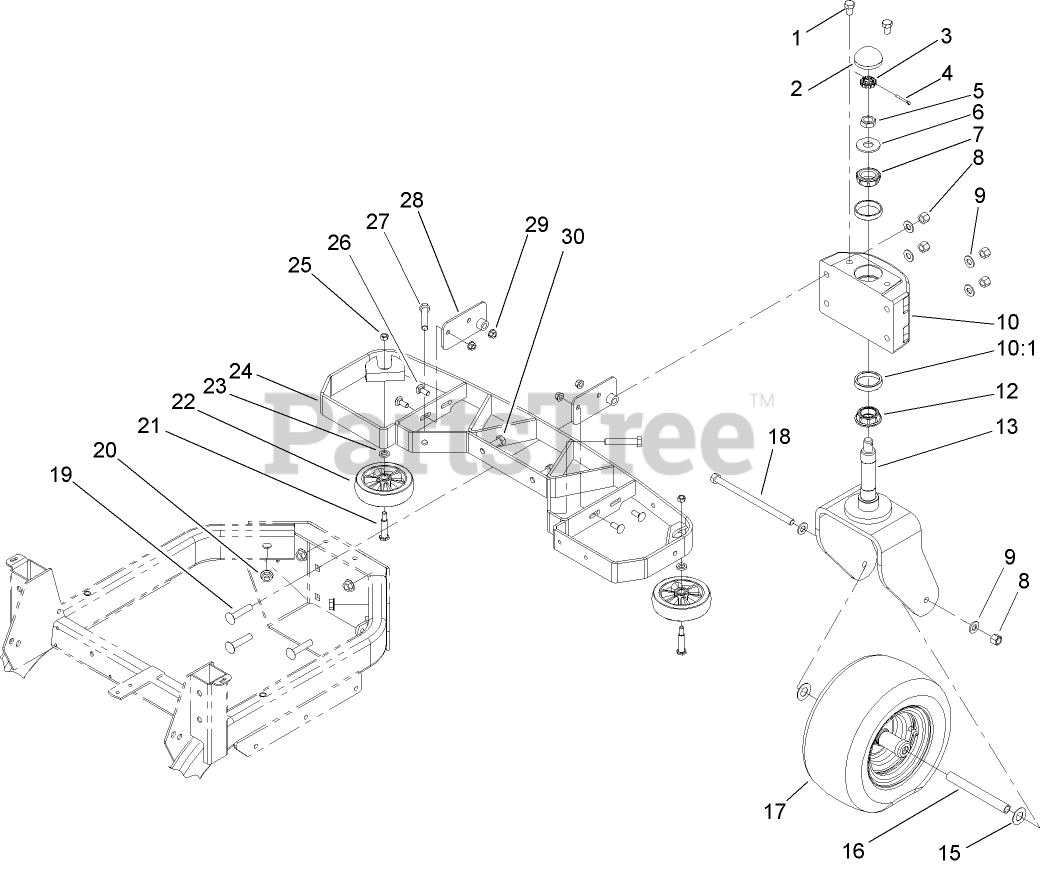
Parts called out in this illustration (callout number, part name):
1	SCREW-HH
2	DUSTCAP
3	NUT-LOCK, RETAINER
4	PIN-COTTER
5	NUT-JAM
6	WASHER-FLAT
7	BEARING-ROLLER, CONE
8	NUT-LOCK, NI
9	WASHER-FLAT
10	SPINDLE HOUSING ASM
10:1	CUP-BEARING, ROLLER
12	BEARING-CONE
13	CASTER FORK ASM
15	WASHER-FLAT
16	TUBE-SPACER, CASTOR
17	Tire And Wheel ASM
18	SCREW-HH
19	SCREW-CARR
20	NUT-HF
21	BOLT-SHOULDER
22	WHEEL ASM
23	Spacer
24	BUMPER ASM
25	NUT-LOCK, SIDE
26	BOLT-CARR
27	SCREW-HH
28	PIVOT ASM
29	NUT-HF
30	SCREW-HH
